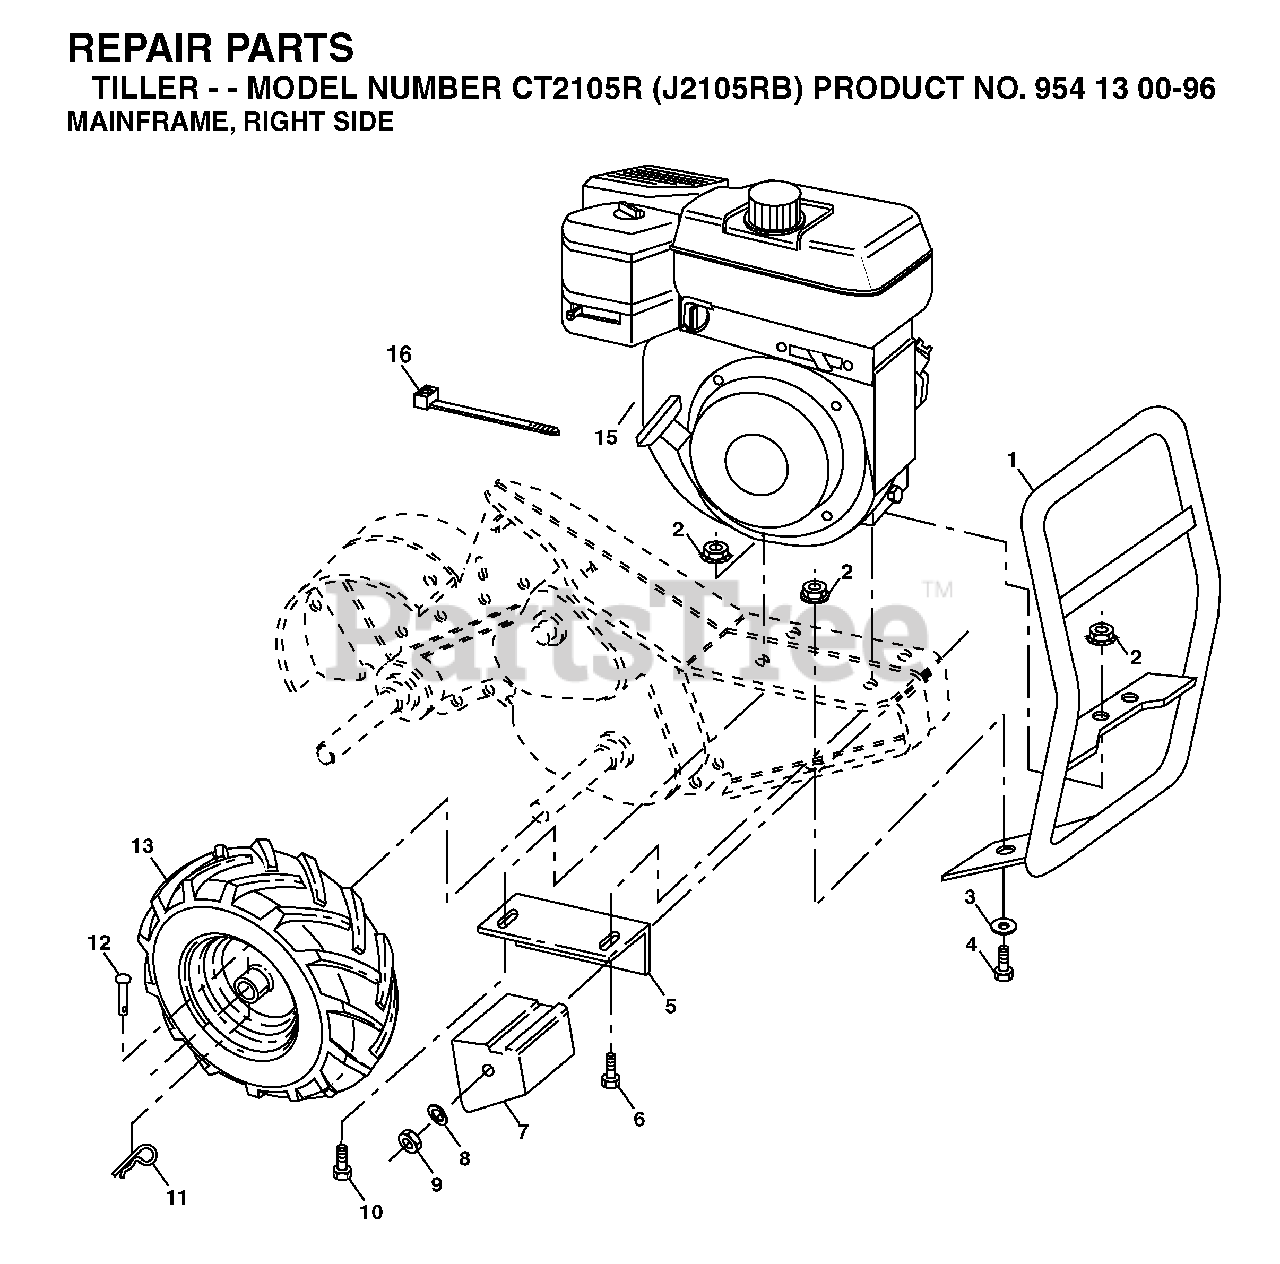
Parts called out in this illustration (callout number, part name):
1	BUMPER.ASM.TILLER.
2	LOCKNUT-FLANGE 5/16-18
3	WASHER
4	BOLT
5	BRACKET RH CRT
6	BOLT, HEX 5/16-18X1-3/4
7	COUNTERWEIGHT, RH
8	WASHER, LOCK 3/8
9	NUT.HEX.3/8-16UNC
10	BOLT
11	RETAINER M
12	RIVET,DRILLED
16	TIE GUIDE
5321243-66	RIM
5321247-18	VALVE STEM LT
